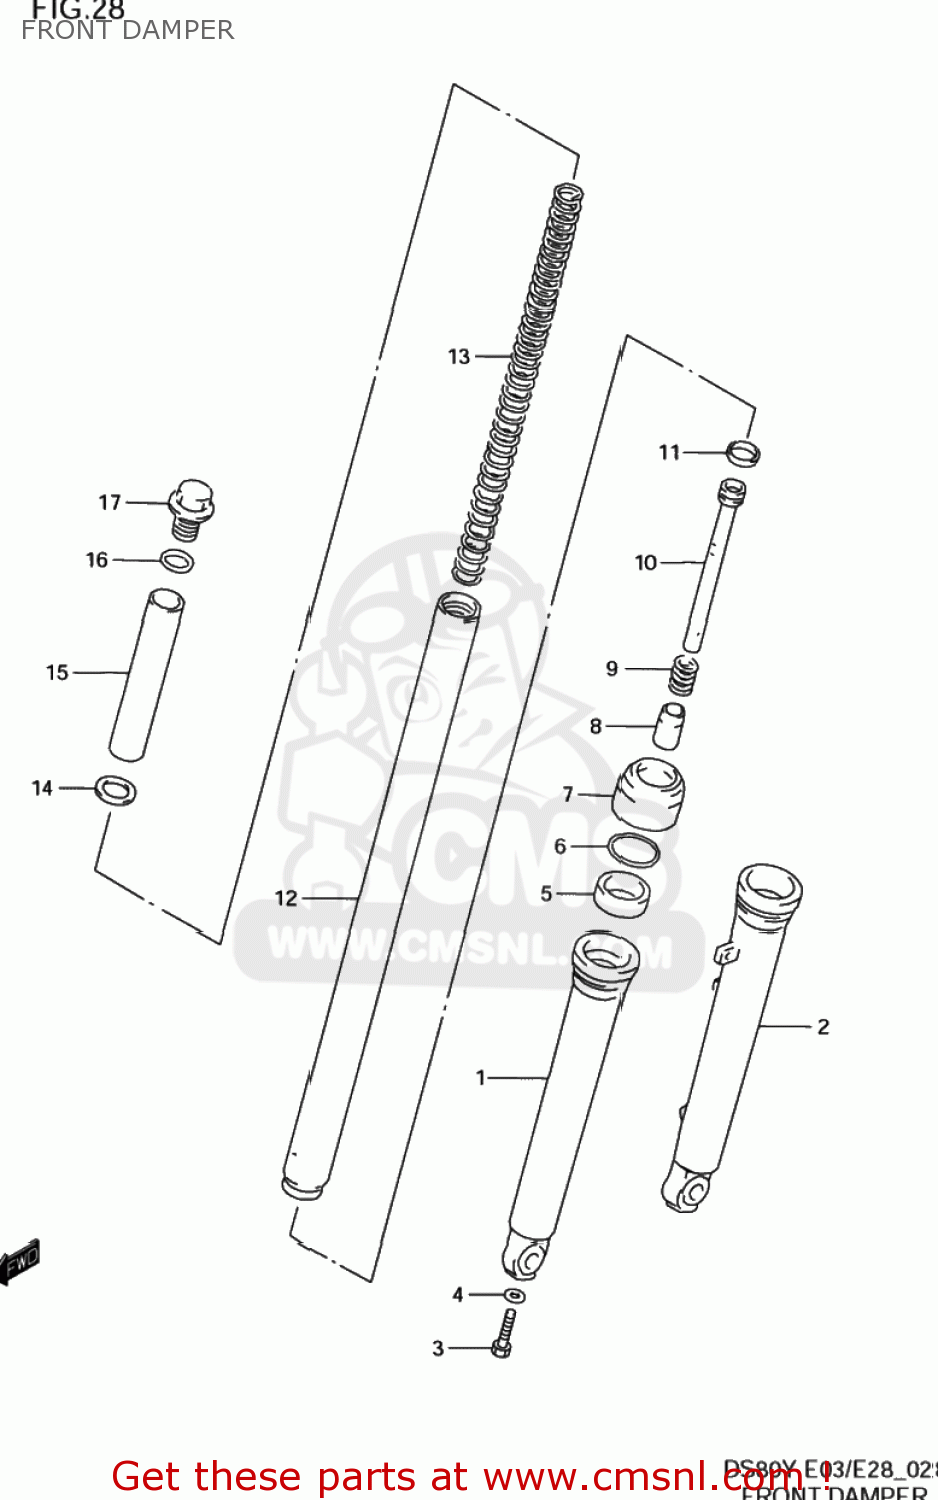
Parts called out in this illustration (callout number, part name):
1	TUBE,OUTER,R
2	TUBE,OUTER,L
3	BOLT(8X27)
4	GASKET (NAS)
5	SEAL,OIL
6	RING,OIL SEAL STOPPER
7	DUST SEAL
8	PIECE,OIL LOCK
9	SPRING,REBOUND
10	CYLINDER,FR FORK
11	RING,PISTON
12	TUBE,INNER
13	SPRING
14	JOINT,SPRING
15	SPACER,SPRING
16	O RING(D:2.4,ID:17.8)
17	CAP
